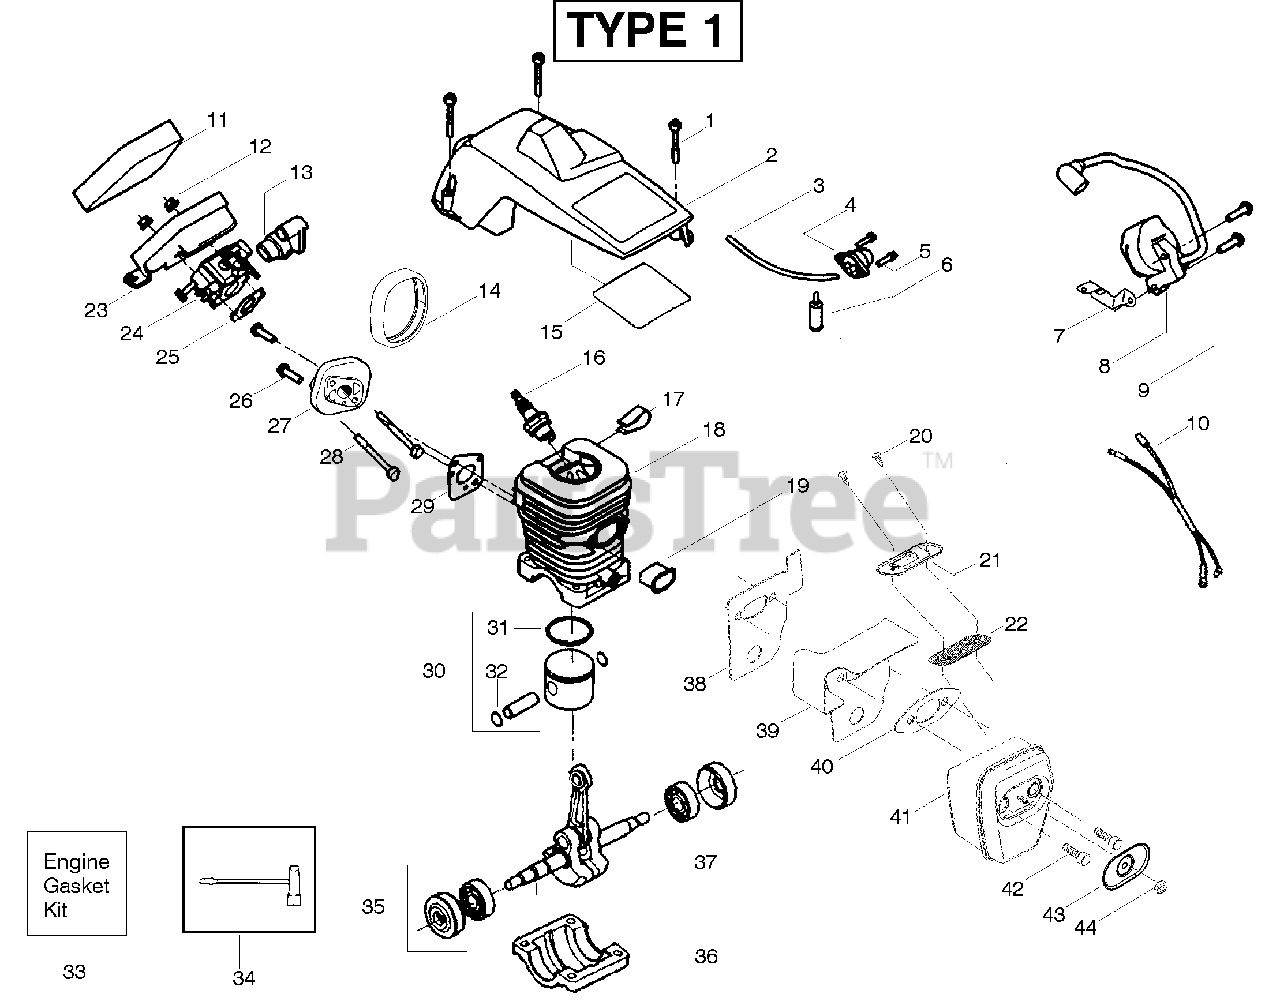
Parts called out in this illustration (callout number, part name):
2	Assy-Cylinder Shield
3	Kit-Fuel Line (Small)
4	Assy- Air Purge
6	Assy-Fuel Pick-up
8	Ignition Module
10	Assy-Wire Harness
11	Foam- Air Filter
13	Grommet-Carb Adjust
14	Seal-Carb Adapter
15	Reflector-Heat
16	Spark Plug (RCJ-7Y)
17	Clip-High Tension Lead
18	Kit-Cylinder
19	Insulator-Heat
20	Screw-Outlet cover
22	Kit-Spark Arrestor
23	Air Filter Housing
24	Kit-Carburetor (WT-599)
24	Kit-Carburetor (W-9A)
27	Carb. Adapter
29	Gasket-Carb Adaptor
30	Kit-Piston
31	Ring-Piston
32	Retainer-Piston Pin
33	Kit-Engine Gasket
34	Bar Wrench
35	Assy-Seal & Bearing
36	Cap-Crankcase
37	Assy-Crankshaft
40	Gasket-Muffler
41	Assy-Muffler
44	Nut-Brass
